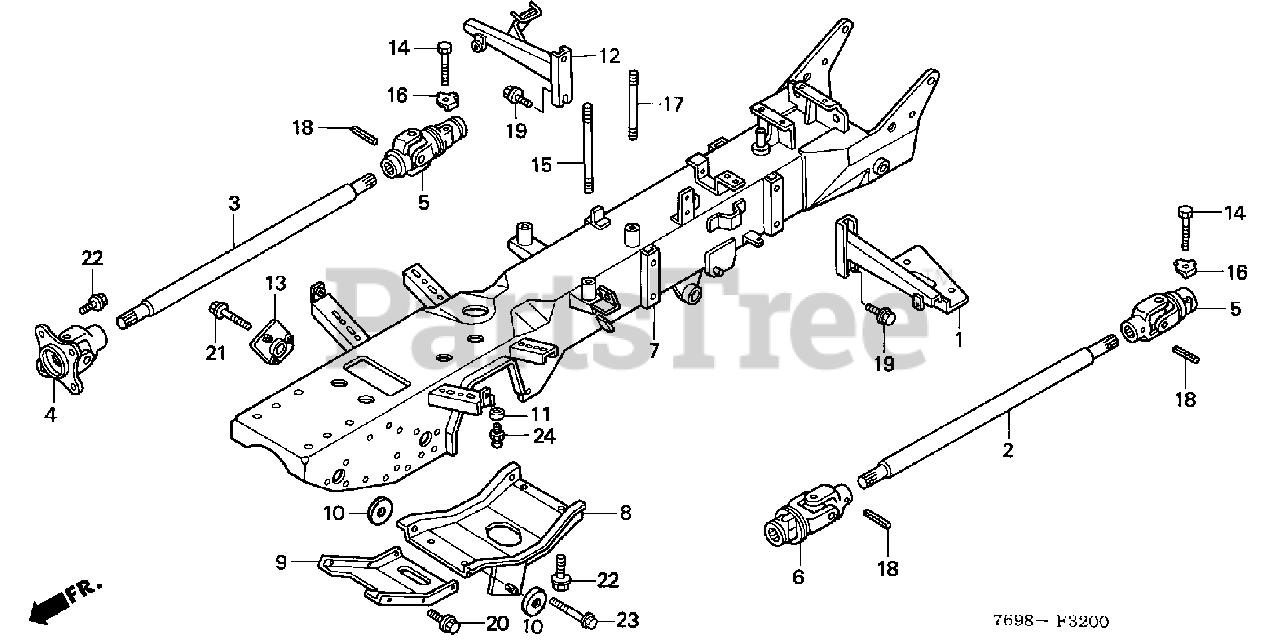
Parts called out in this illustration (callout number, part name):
1	BRACKET A, FUEL TANK
2	SHAFT, PROPELLER (B)
3	SHAFT A, PROPELLER
4	JOINT, UNIVERSAL
5	JOINT E, UNIVERSAL
6	JOINT F, UNIVERSAL
8	COVER A, FRAME (LOWER)
9	COVER B, FRAME (LOWER)
10	COLLAR, FR. ENGINE HANGER (A)
11	COLLAR (6.5X11X3)
12	BRACKET, OIL TANK
13	PIVOT, LIFT LINK
14	BOLT, SPECIAL (8MM)
15	BOLT, STUD (10X128)
16	WASHER, LOCK (8MM)
17	BOLT, STUD (10X90)
18	PIN, SPRING (6X32)
19	BOLT, FLANGE (8X14)
20	BOLT, FLANGE (8X16)
21	BOLT, FLANGE (8X20)
22	BOLT, FLANGE (10X20)
23	BOLT, FLANGE (10X28)
24	FITTING, GREASE (A.76)
